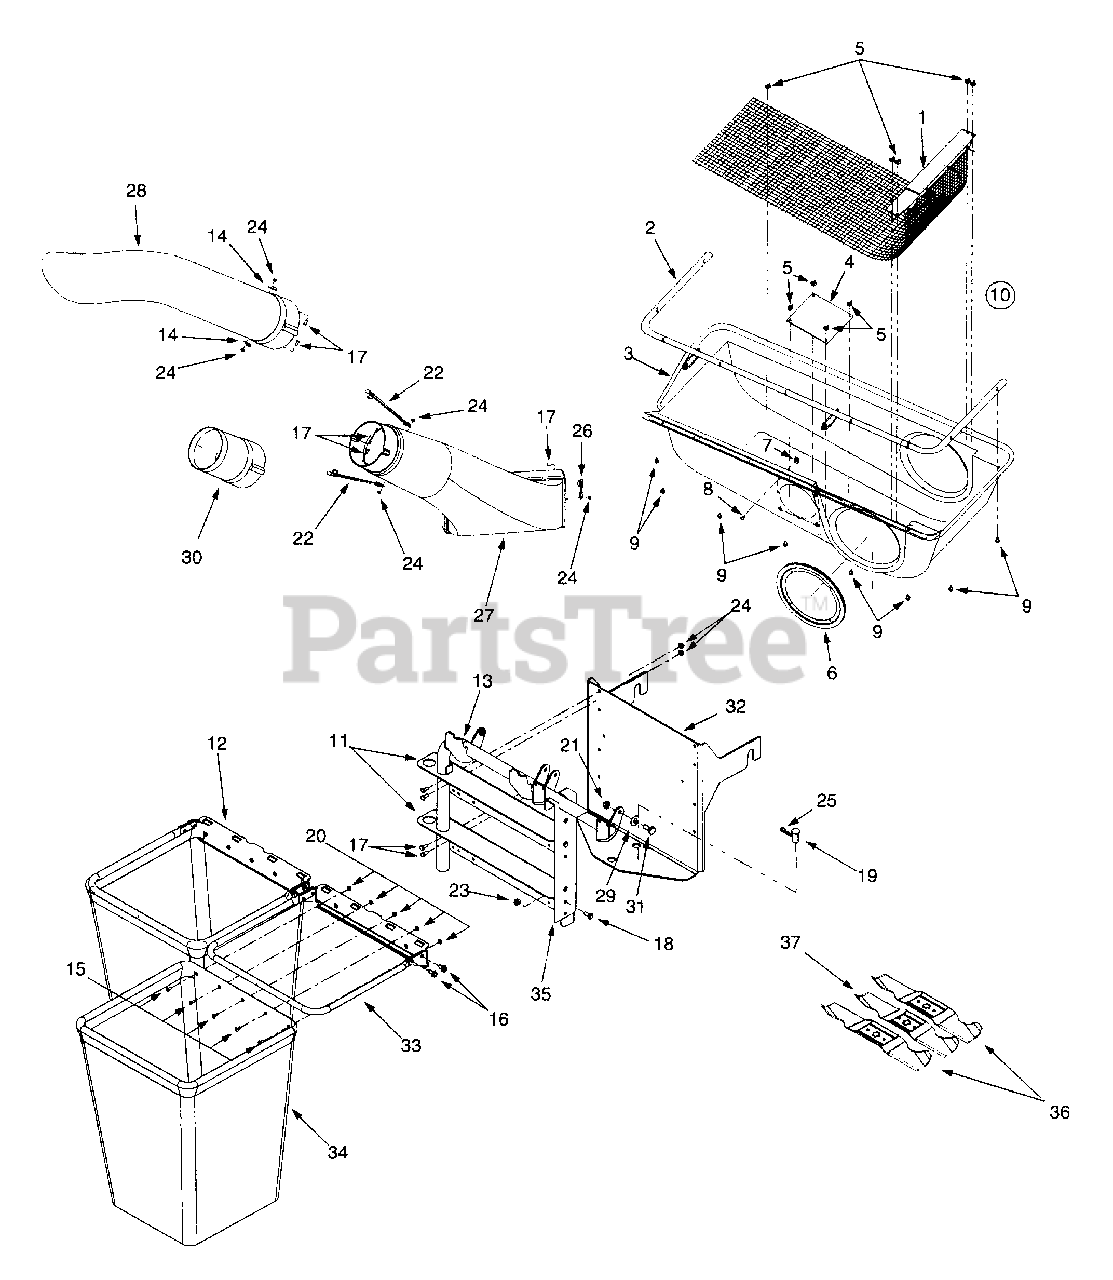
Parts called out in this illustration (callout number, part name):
3	Grass Catcher Cover (Model 625)
4	Plastic Plate, 1/8 x 5.6 sq.
5	Zip Twist Fastener
6	Tube Seal (Model 625)
7	U-Type Speed Nut, #10-24
8	Screw, #10-24 x .5
9	Hex Screw, 1/4-20 x .5 (Model 625)
10	Cover Assembly (Model 626)
14	Retainer Hook Bracket
15	Screw, #10-24 x .5
16	Self Tapping Screw, 5/16-18 x .625
17	Hex Cap Screw, 1/4-20 x .62
18	Hex Cap Screw, 5/16-18 x .75
19	Clevis Pin
20	Hex Sems Nut, 10-24
21	Hex Flange Lock Nut, 3/8-16
22	Retainer Strap Assembly
23	Hex Flange Lock Nut, 5/16-18
24	Hex Flange Lock Nut, 1/4-20
25	Internal Cotter Pin, .148 x 3
26	Retainer Strap Assembly
27	Discharge Chute (Model 625)
28	Chute Tube (Model 625)
29	Bell Washer
30	Extension Tube (Model 625)
31	Shoulder Screw, .50 x .27, 3/8-16
34	Bag
36	Star Center Blade, 16.28 (Model 626)
37	Star Center Blade, 14.88 (Model 626)
